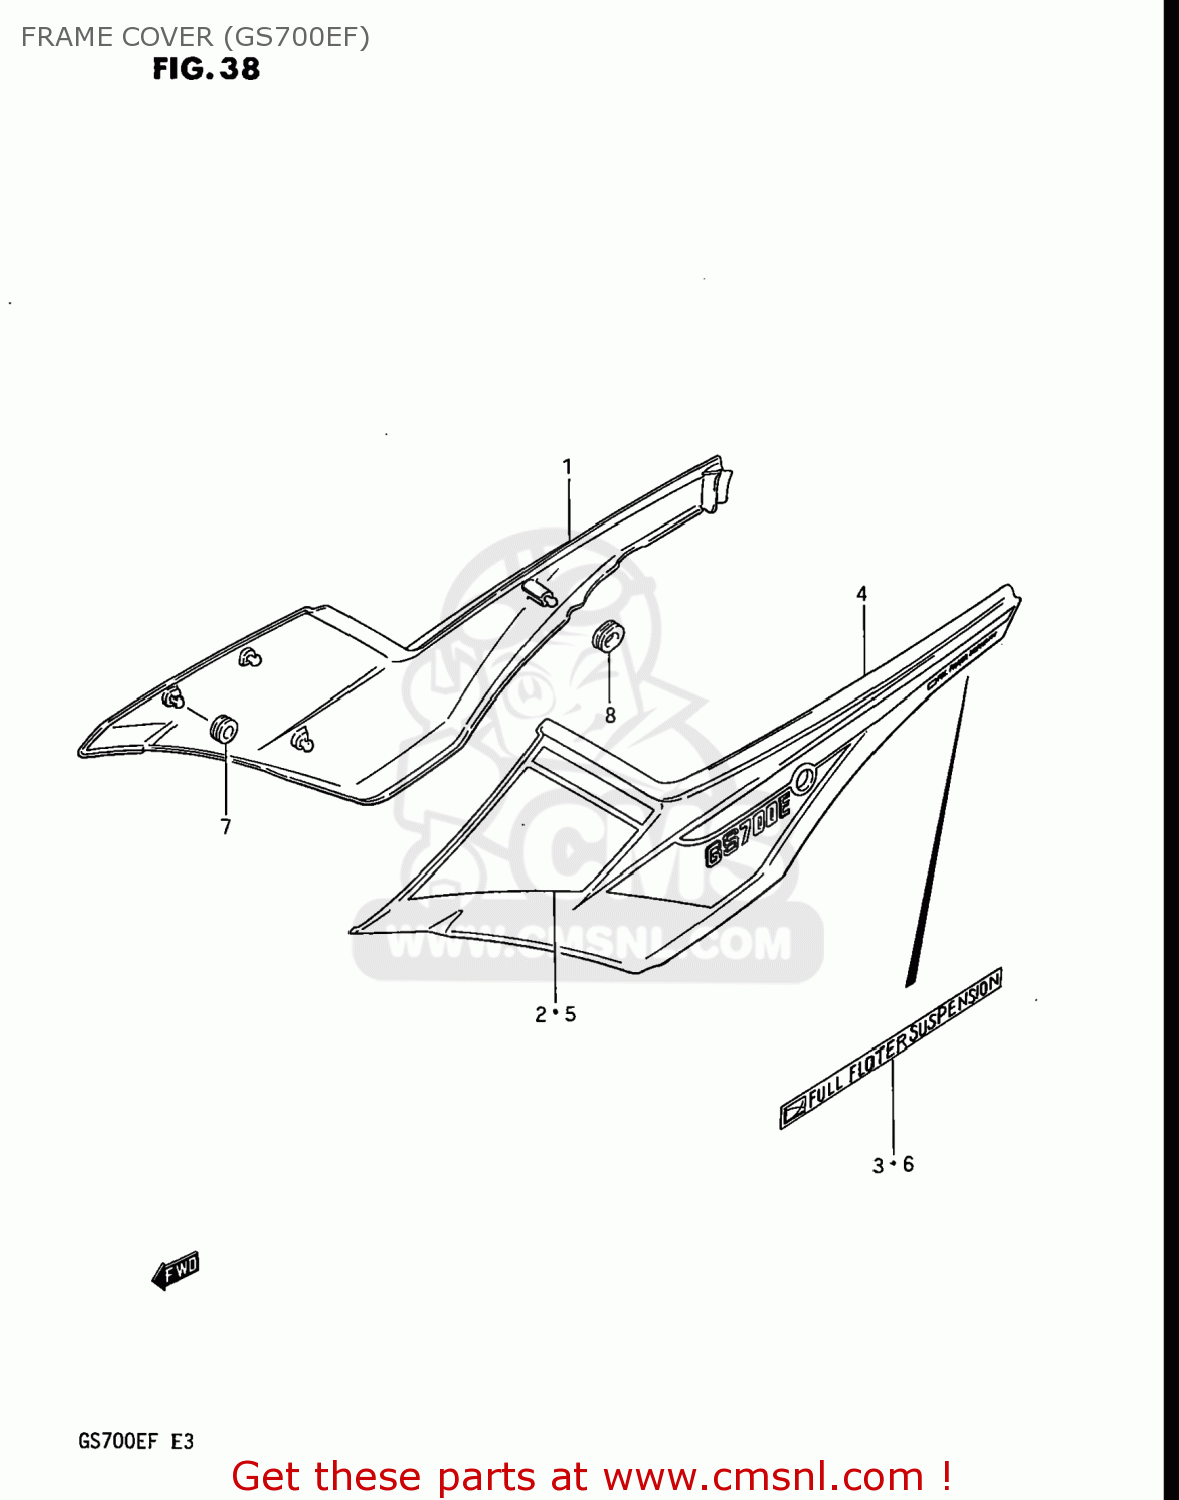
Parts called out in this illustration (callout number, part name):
1	COVER,FRAME,RIGHT
2	TAPE SET,FRAME COVER,RIGHT
3	EMBLEM
4	COVER,FRAME,LEFT
5	TAPE SET,FRAME COVER,LEFT
6	EMBLEM
7	CUSHION
8	CUSHION
